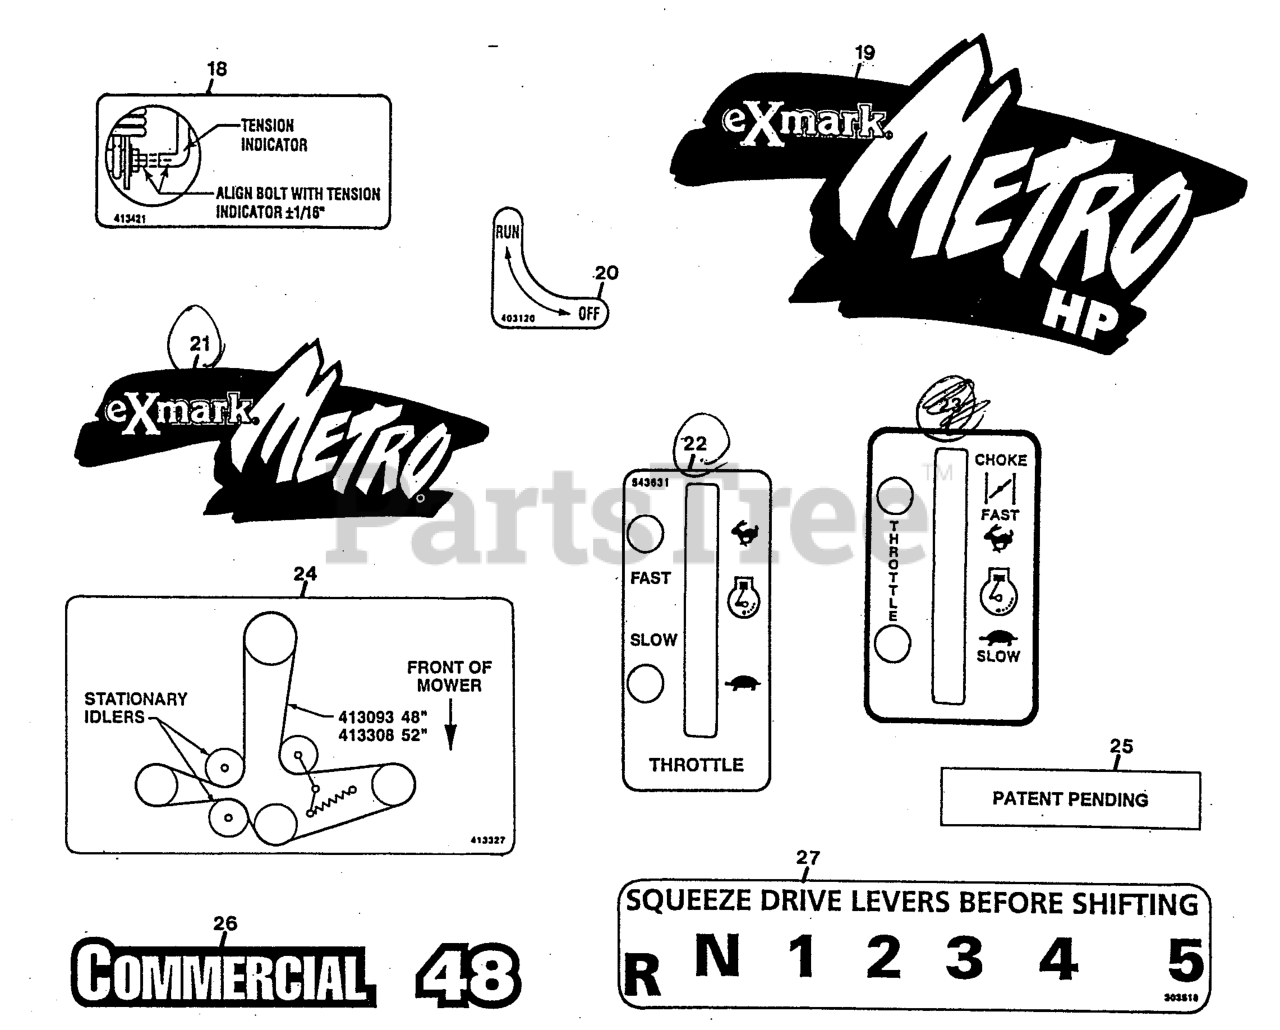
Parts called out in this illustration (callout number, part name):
18	Decal, Indicator
19	Decal, Mhp-Swash
20	Decal, Off/Run
21	Decal, Sm Metro Console
22	Decal, Throttle
23	Decal, Throttle/Choke
24	Decal, Belt Routing (48" & 52")
25	Decal, Patent Pending
26	Decal, Commercial 48
27	Decal, Shifter
